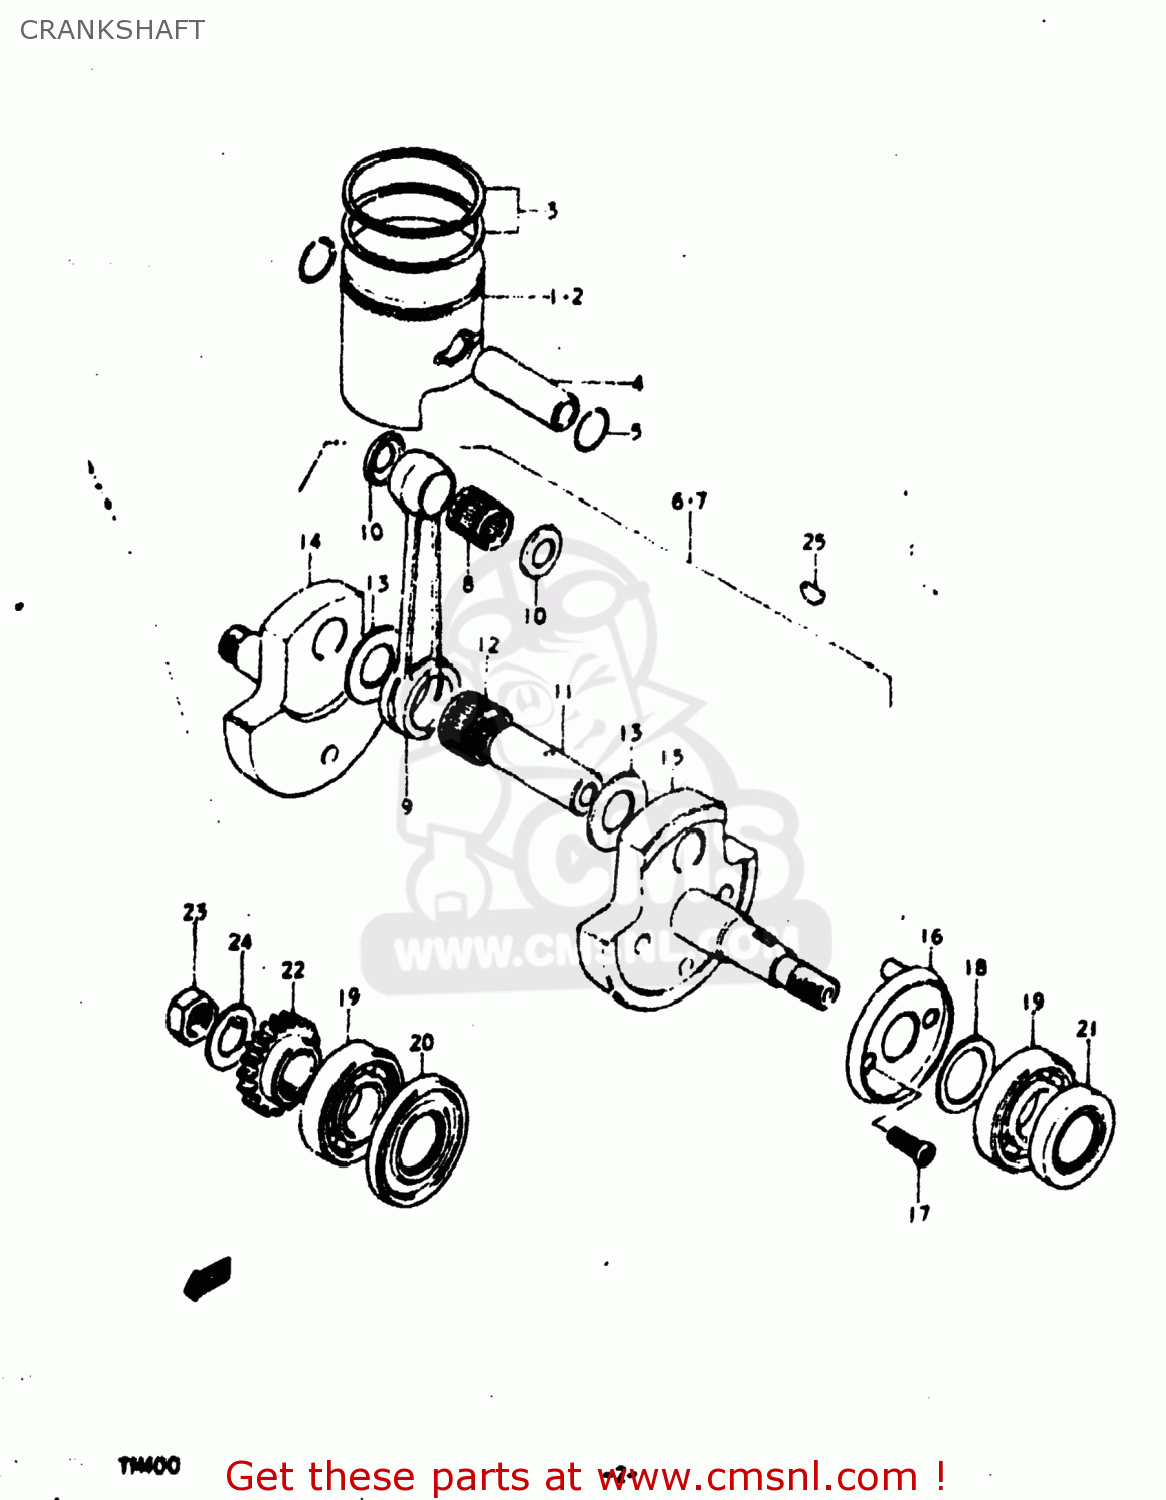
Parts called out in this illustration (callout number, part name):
1	PISTON
2	PISTON
3	RING SET,PISTON
4	PIN,PISTON
5	CIRCLIP
6	CRANKSHAFT SET
7	CRANKSHAFT ASSEMBLY
8	BEARING
9	CONNECTING ROD
10	WASHER
11	PIN,CRANK
12	BEARING
13	WASHER
14	CRANKSHAFT
15	CRANKSHAFT,LEFT
16	PLATE,CRANKSHAFT OIL GUIDE
17	SCREW
18	WASHER
19	BEARING
20	OIL SEAL
21	OIL SEAL
22	GEAR,PRIMARY DRIVE
23	NUT (20MM)
24	WASHER
25	KEY
